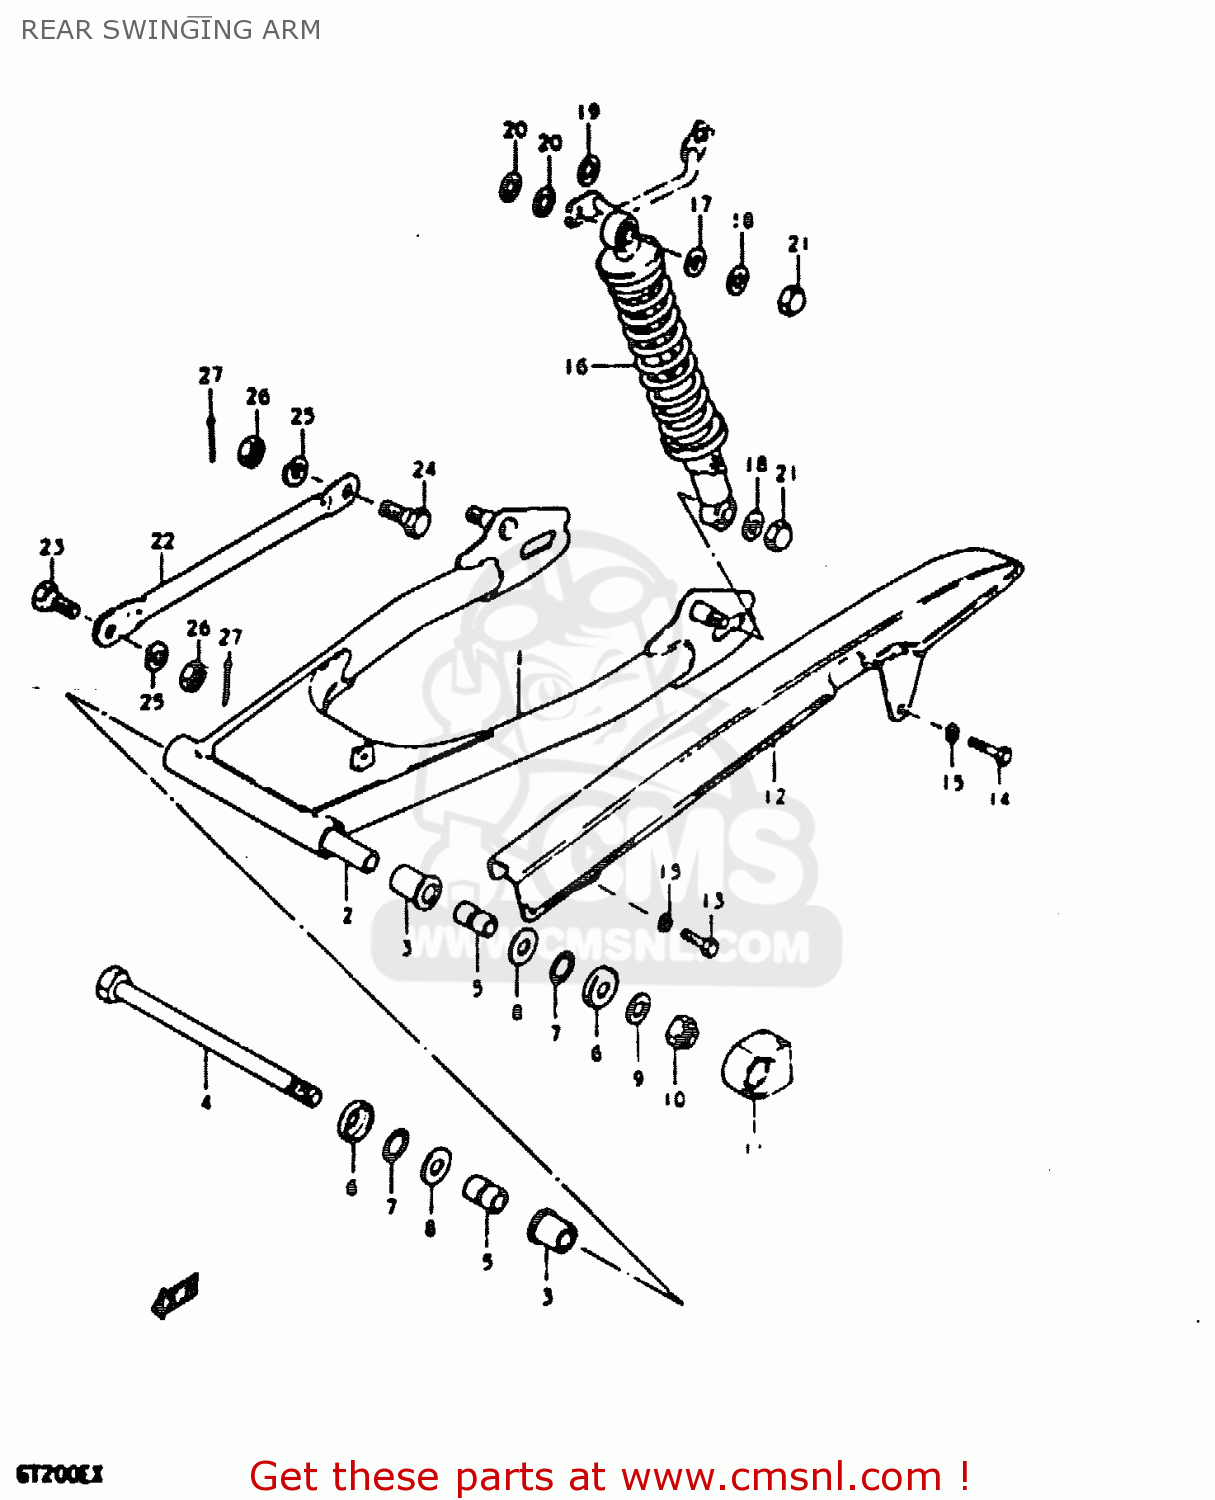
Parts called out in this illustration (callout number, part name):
1	REAR SWINGING ARM SET
2	SPACER,SWING ARM,CENTER
3	BUSH
4	SHAFT, PIVOT
5	SPACER,RR SWGARM PIVOT
6	COVER,SWGARM BUSH DUST SEAL
7	O RING(D:2,ID:24.5)
8	WASHER(12.5X24X2.3)
9	WASHER
10	NUT 12MM
11	BUFFER,CHAIN TOUCH DEFLECTOR
12	CASE,CHAIN
13	BOLT
14	BOLT
15	LOCK WASHER
16	SHOCK ABSORBER ASSY, REAR
17	WASHER(10.5X24X3.2)
18	WASHER
19	WASHER (12.5X24X3.2)
20	WASHER
21	NUT, LOWER LH
22	TORQUE LINK, REAR
23	BOLT(8X22.5)
24	BOLT(8X26.5)
25	LOCK WASHER
26	NUT
27	PIN 20X20
